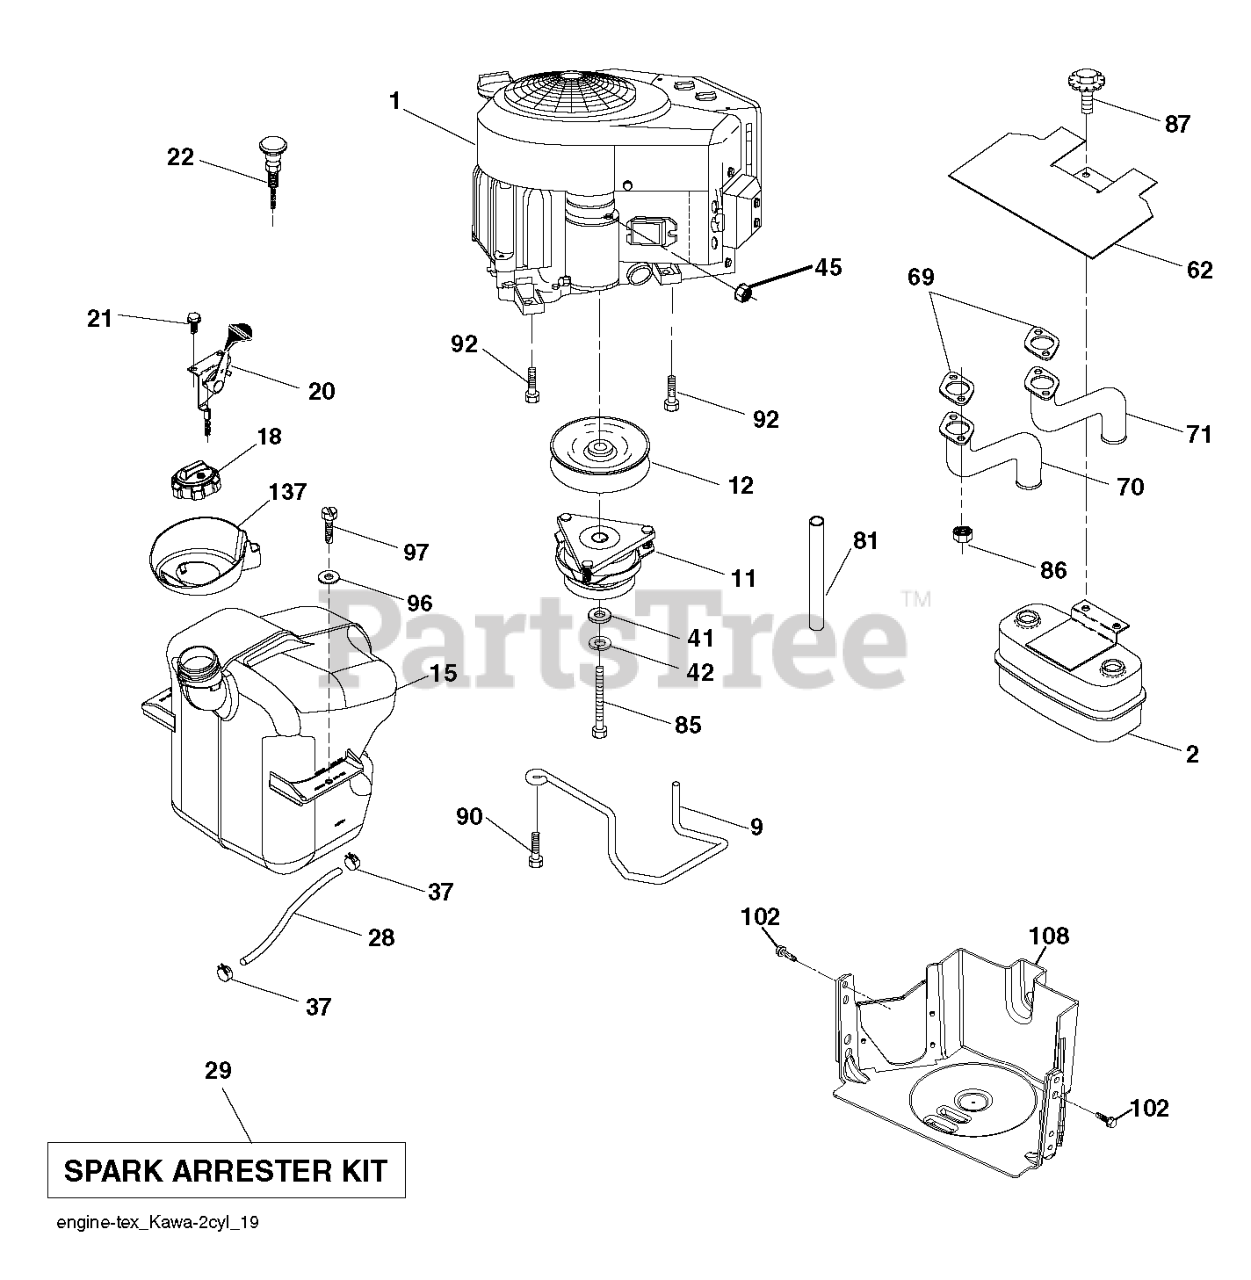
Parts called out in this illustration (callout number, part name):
2	MUFFLER.ASM.TWN.EXTNDED.DFLCTR
9	KEEPER.BELT.ENGINE.4.2
11	CLUTCH.ELECTRIC.LT.48"*
12	PULLEY.ENGINE.TUFFTORQ
15	FUEL TANK TANK. ASSEMBLY. EXTE
18	CAP.ASM.FUEL.2.25"TOP.TURN
20	CONTROL.THROTTLE.COBRA.BLACK
21	SCREW.#10 X 0.750.BOS
22	CONTROL.CHOKE.ERGO.PUSH-IN.BLA
28	LINE.FUEL.20
29	KIT.SPARK ARRESTOR 794945 B&S
37	HOSE CLAMP
42	LOCKWASHER
45	NUT
62	SHIELD.HEAT.MUFFLER
70	TUBE.EXHAUST.LH.FR961/FR730
71	TUBE.EXHAUST.RH.FR961/FR730
81	TUBE, DRAIN OIL ASM.
85	BOLT HEX 7/16-20X4-1/4"
86	NUT.HEX.FLANGE.TOPLOCK
87	BOLT.5/16-18UNCX3/4 W/SEMS.BLK
90	SCREW 3/8-16X1
92	SCREW 3/8-16X1
96	WASHER
97	SCREW HEXWSHR 1/4-20X3/4
102	SCREW 5/16-18X1
108	COVER PULLEY
